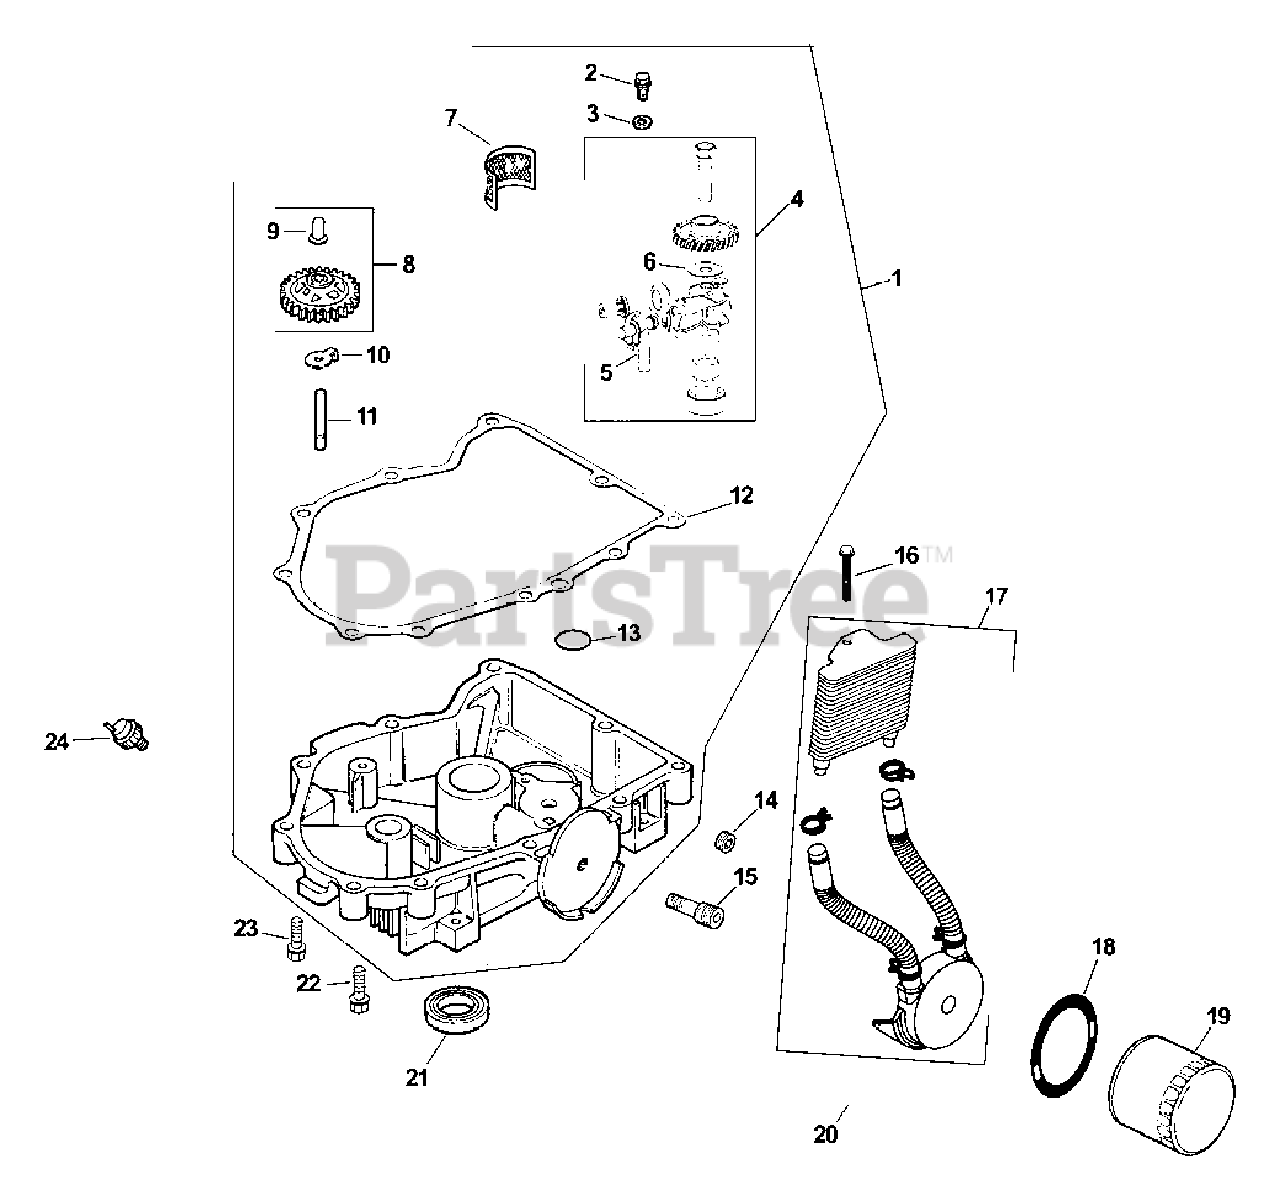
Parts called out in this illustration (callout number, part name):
1	Oil Pan w/Gasket Kit
2	Hex Flange Screw (M6 x 1.0 x 25)
3	Plain Washer 6mm
4	Oil Pump Assembly
5	Oil Pickup Tube
8	Governor Gear Kit
9	Governor Regulating Pin
11	Governor Gear Shaft
12	Oil Pan Gasket
14	Hex Plug 3/8"
15	Oil Filter Nipple
16	Hex Cap Screw (M6 x 1.7 x 18)
17	Oil Cooler
19	Oil Filter
20	Plastic Nut
21	Oil Seal (PTO End)
22	Hex Flange Screw (M8 x 1.25 x 45)
23	Hex Flange Screw (M8 x 1.25 x 45)
24	Oil Pressure Switch
